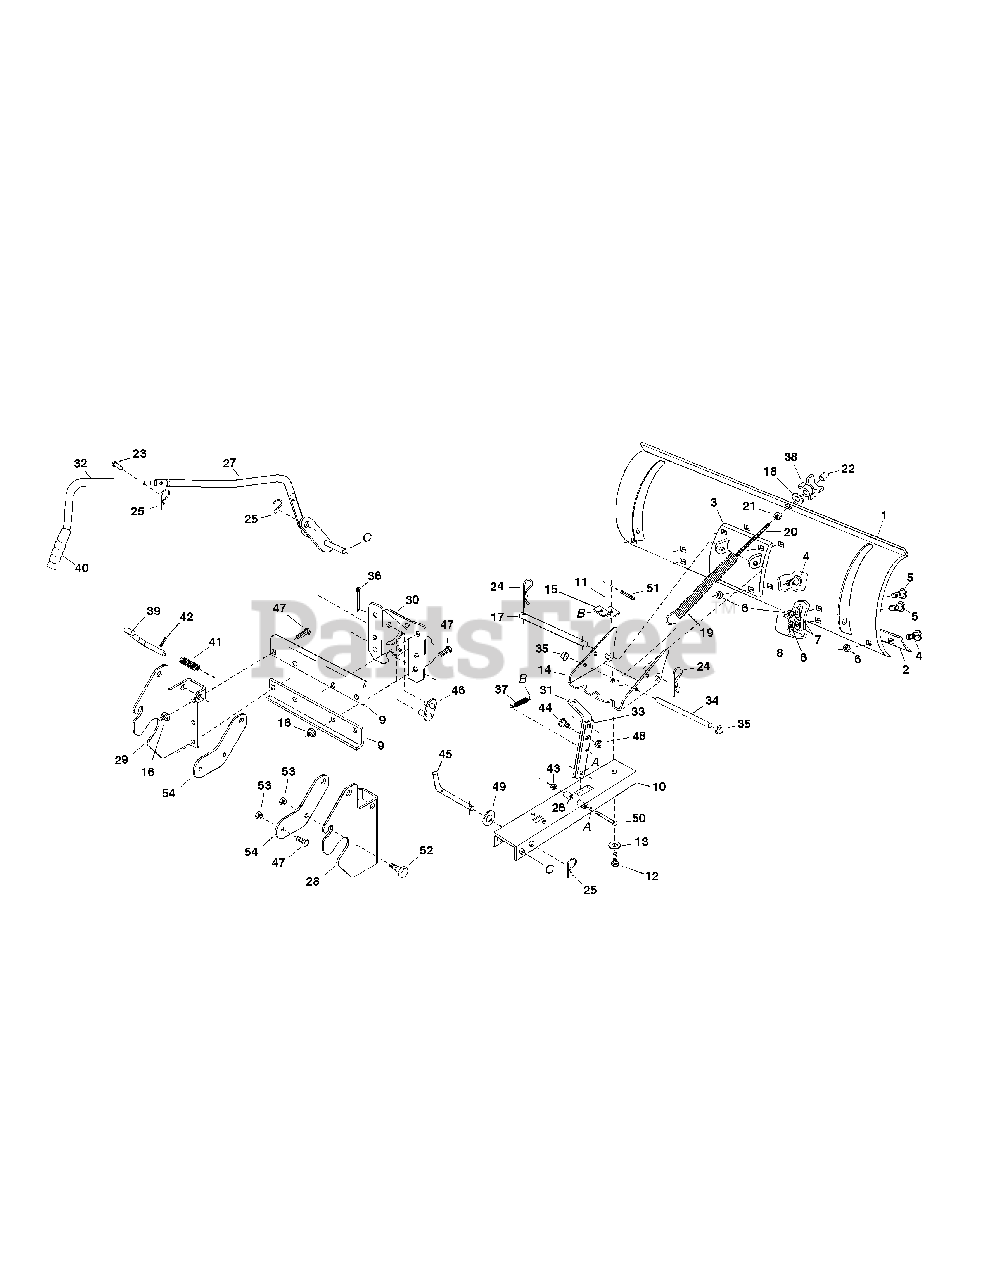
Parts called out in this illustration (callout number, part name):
1	Blade - 46"
2	Wear Plate - 46"
3	Reinforcement Plate Assembly
4	Bolt, Carriage 5/16-18 x 3/4
6	Hex Lock Nut 5/16-18 Thread
7	Washer, 5/16"
8	Skid Shoe
9	Bracket, Angle Support
10	Push Channel
11	Hex Lock Nut6, 1/2-13 Thread
12	Bolt, Special Pivot
14	Plate, Pivot 7 Ga
15	Bracket, Spring Mt.
16	Flanged Lock Nut, 3/8-16 Thread
17	Shaft, Pivot
18	Washer, 3/8" STD
19	Spring, Blade Adjust
20	Hex Bolt, 3/8-16 x 3 -1/2"
21	Hex Nut, 3/8-16 Thread
22	Plastic Cap
23	Pin, Clevis 1/4" x 1-1/2"
24	Pin Hair Cotter #4 (1/8")
25	Pin Hair Cotter #3 (3/32")
26	Spacer, .28 ID x 1"
27	Lift Handle Assembly, Lower
28	Hitch Bracket, RH
29	Hitch Bracket, LH
31	Angle Lock Bar (Long)
32	Lift Handle Upper
33	Angle Lock Bar (Short)
34	Spring Mount Rod
35	Palnut 3/8
36	Cotter Pin 1/8" x 1
37	Angle Lock Spring
39	Pin, Attachment
40	Handle, Grip
41	Spring, Compression
42	Pin, Spring 3/16" x 1
43	Hex Lock Nut 1/4-20 Thread
45	Channel Pivot Pin
46	Lift Link Assembly
47	Hex Bolt, 3/8-16 x 3/4"
48	Hex Lock Nut, 3/8"-16 Thread
50	Hex Bolt, 1/4-20 x 3 1/4" LG. GR 5
51	1/4" x 1" Spring Pin
52	Shoulder Bolt 3/8-16 x 1/2"
53	Hex Lock Nut, 3/8"-16 Thread
54	Blade Mounting Bracket Kit
